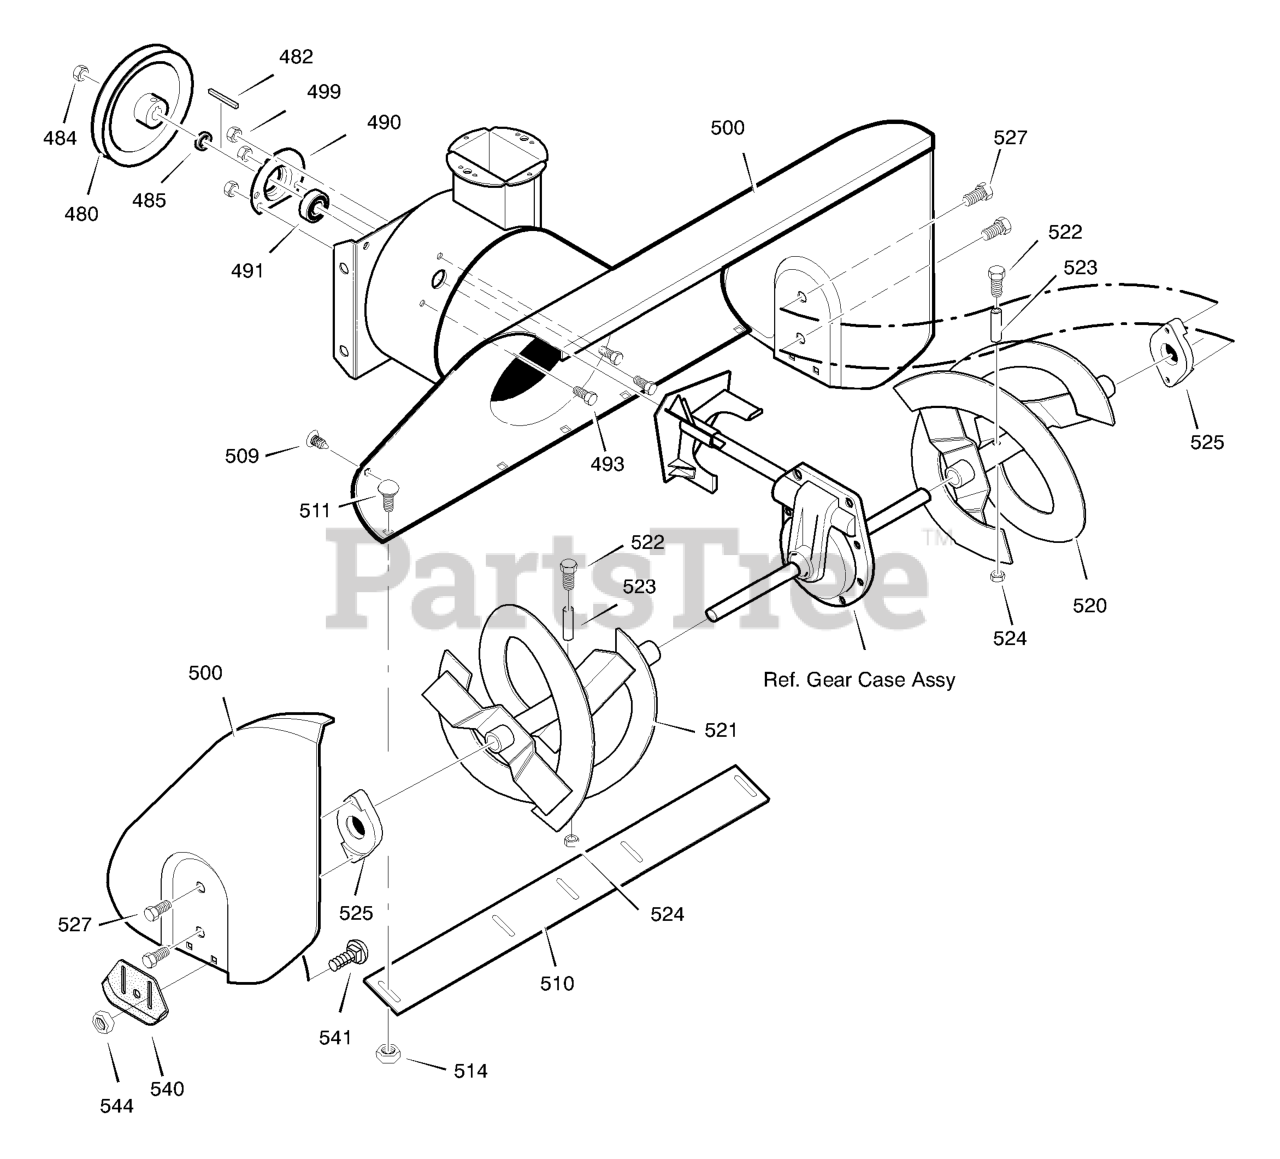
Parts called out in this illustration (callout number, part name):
480	PULLEY, 4L 8.40 OD
482	KEY, SQUARE 3/16 X 3/4
484	NUT, 1/2-20
485	SPACER, FRICTION PULLEY
490	RETAINER, BALL BRNG
491	BEARING, BALL
493	BOLT, HEX 5/16-18X .50
499	NUT, 5/16-18 HEXWDFLLK
500	HOUSING, ASSY
509	PLUG, CHRISTMAS TREE
510	BLADE, SCRAPER
511	BOLT, 5/16-18X.75
514	NUT, 5/16-18
520	AUGER, ASSY, LH
521	AUGER, ASSY, RH
522	SCREW, 1/4-20 X 1.75
523	SPACER, SLEEVE
524	NUT, 1/4-20
525	BEARING,FLANGE
527	SCREW, 5/16-18 x 0.75
540	SKID, HEIGHT ADJUST
541	BOLT, 5/16-18 X .75
544	NUT, 5/16-18
